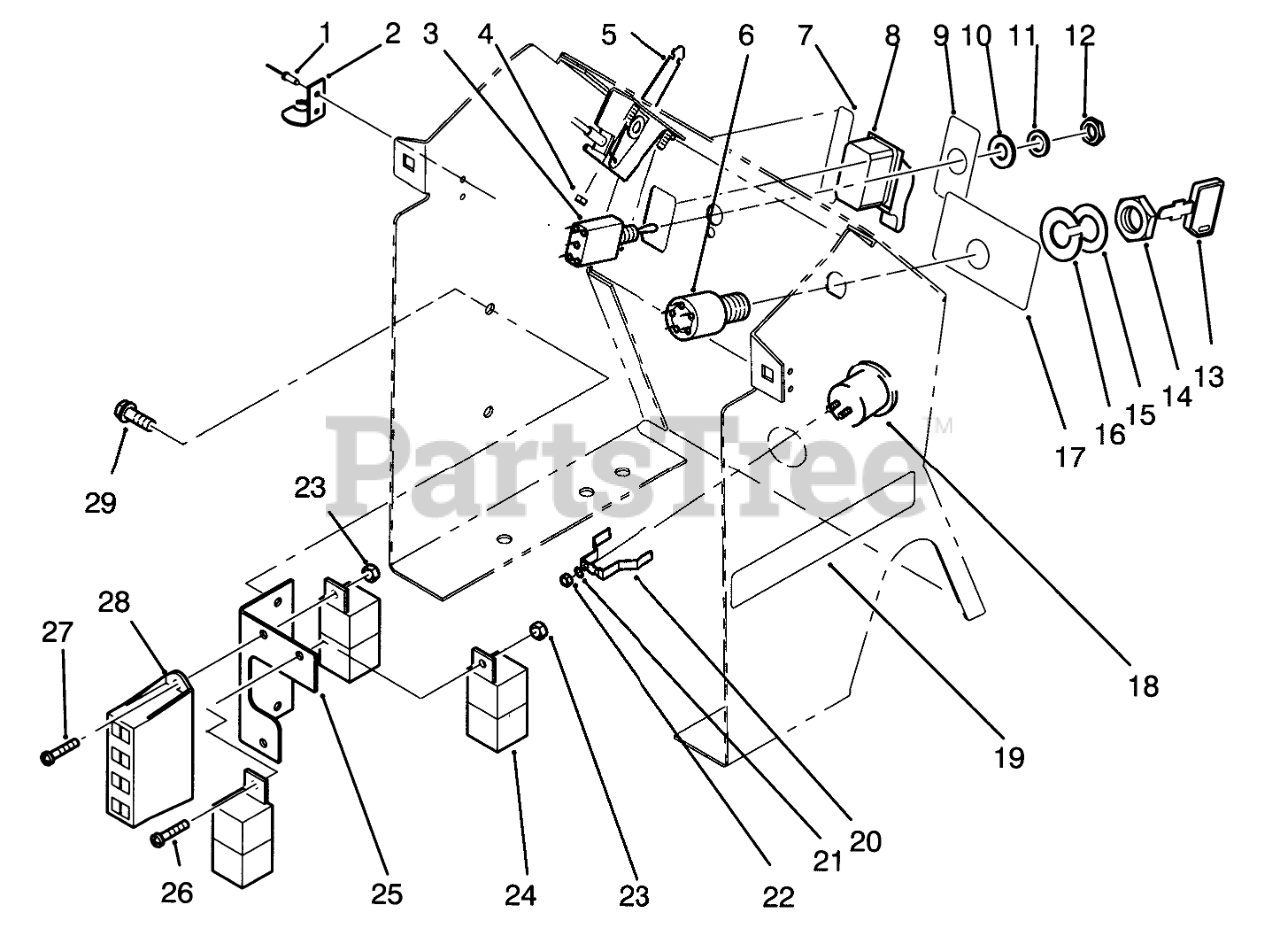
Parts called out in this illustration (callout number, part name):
1	POPRIVET 1/8X 1/8 BK
2	KEEPER-LATCH
3	SWITCH-LIGHTS
4	Nut
5	CONTROL-THROTTLE
6	Switch-Ignition, Assembly (Incl. Ref. #6 & 13-17)
7	DECAL-PTO
8	PTO-SWITCH W/COVER
9	DECAL-LIGHTS
10	WIRE ASSY
11	Washer
13	KEY-IGNITION
15	Washer
16	LOCKWASHER
17	DECAL-IGNITION
18	HOUR-METER
19	DECAL-MODEL 5-SPEED
20	CLAMP-HOUR METER
21	WASHER-LOCK
22	Nut
23	Nut
24	RELAY
25	Bracket-Fuse Holder
26	SCREW-PPH
27	Screw
28	FUSE-HOLDER 4 WAY
29	TRS-1/4-20X1/2 BLACK
